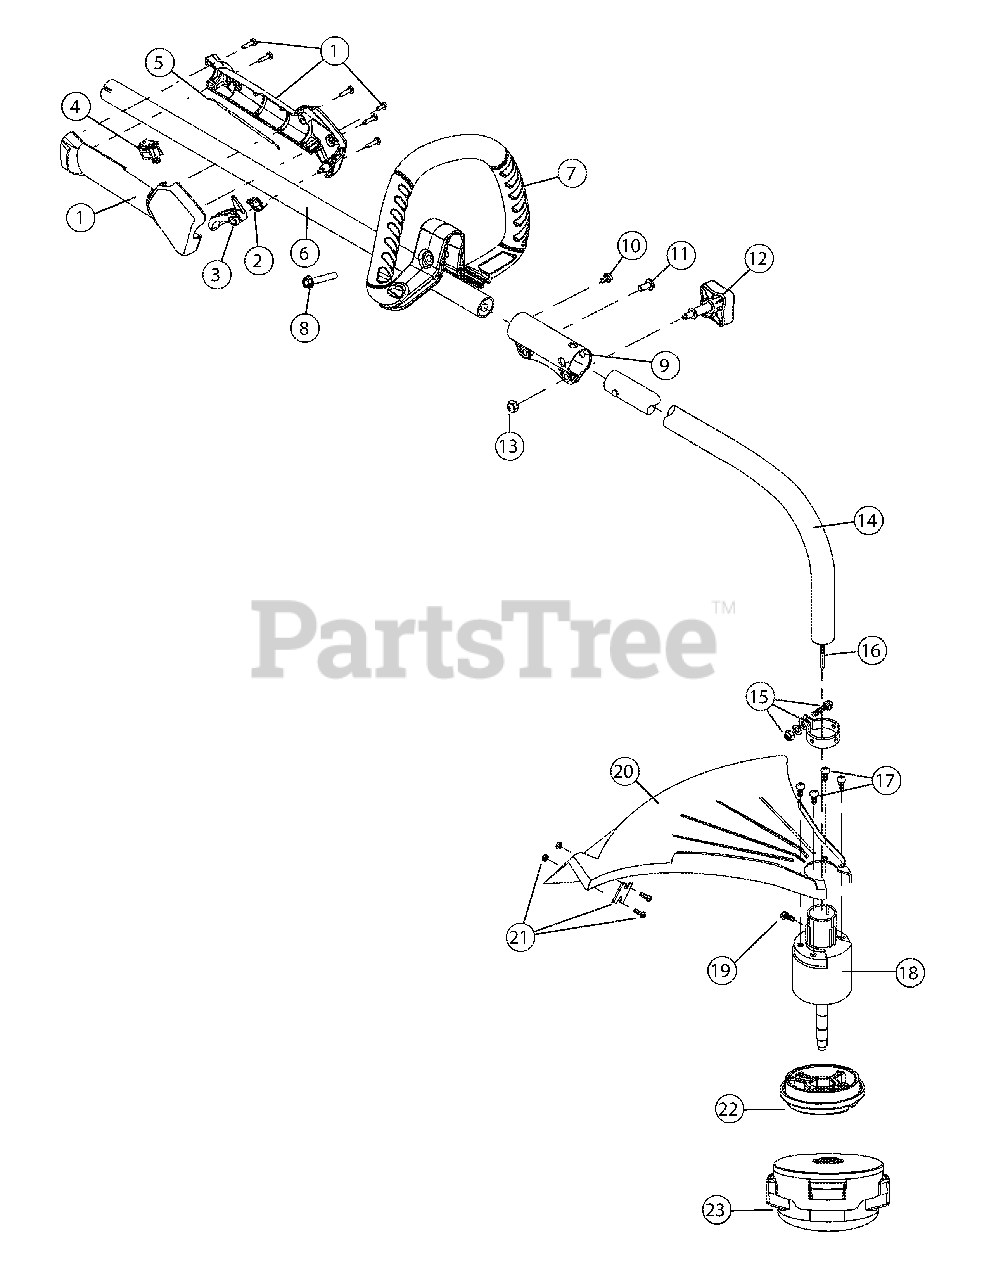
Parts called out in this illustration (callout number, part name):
1	Throttle Housing Assembly
2	Throttle Trigger Spring
3	Throttle Trigger
5	Throttle Cable Assembly
6	Upper Drive Shaft Housing Assembly
7	D-Handle Assembly
9	Split boom Coupler
12	Adjustment Knob
13	Knob Retaining Nut
14	Lower Drive Shaft Housing Assembly
15	Lower Clamp Assembly
16	Lower Flexible Drive Shaft
17	Shield Mounting Screw
18	Bushing Housing Assembly
19	Anti-Rotation Screw
20	Shield Assembly
21	Blade Assembly
23	Spool Assembly
